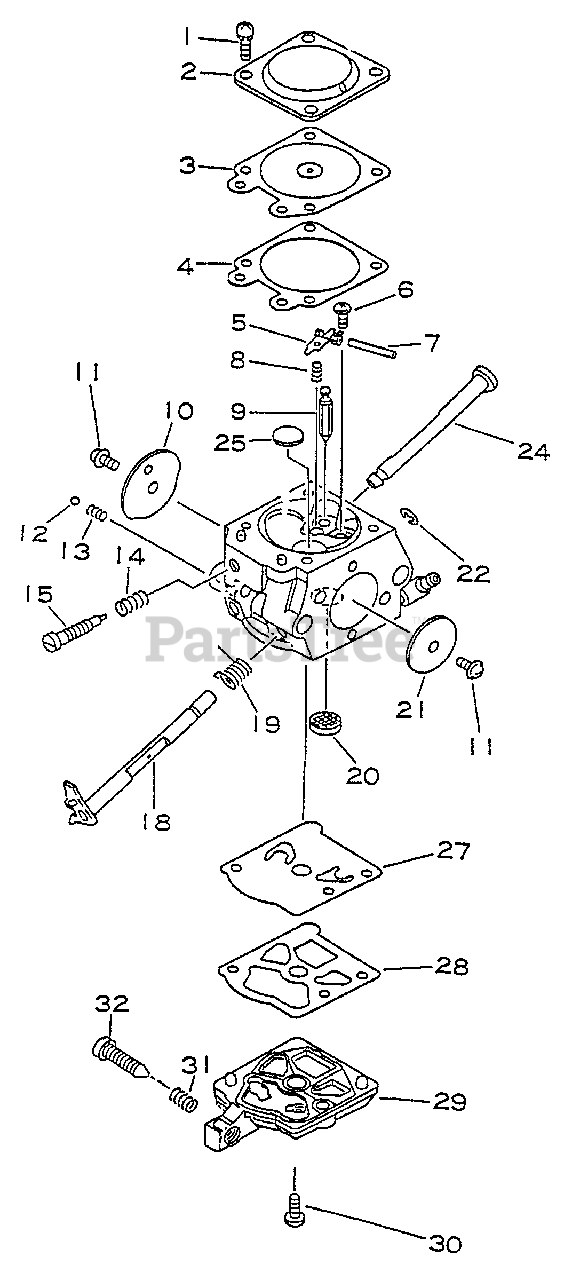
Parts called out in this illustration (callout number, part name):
1	SCREW
2	COVER, METERING DIAPHRAGM
3	DIAPHRAGM, METERING
4	GASKET, METERING
5	LEVER, METERING
6	SCREW, METERING LEVER PIN
7	PIN, METERING LEVER
8	SPRING, METERING LEVER
9	VALVE, INLET NEEDLE
10	VALVE, CHOKE
12	BALL, CHOKE FRICTION
14	SPRING, NEEDLE
15	NEEDLE, LOW SPEED
18	SHAFT, THROTTLE
19	SPRING, THROTTLE RETURN
20	STRAINER
21	VALVE, THROTTLE
24	SHAFT, CHOKE
25	PLUG, WELCH
29	COVER, FUEL PUMP
32	SCREW, IDLE ADJUST
